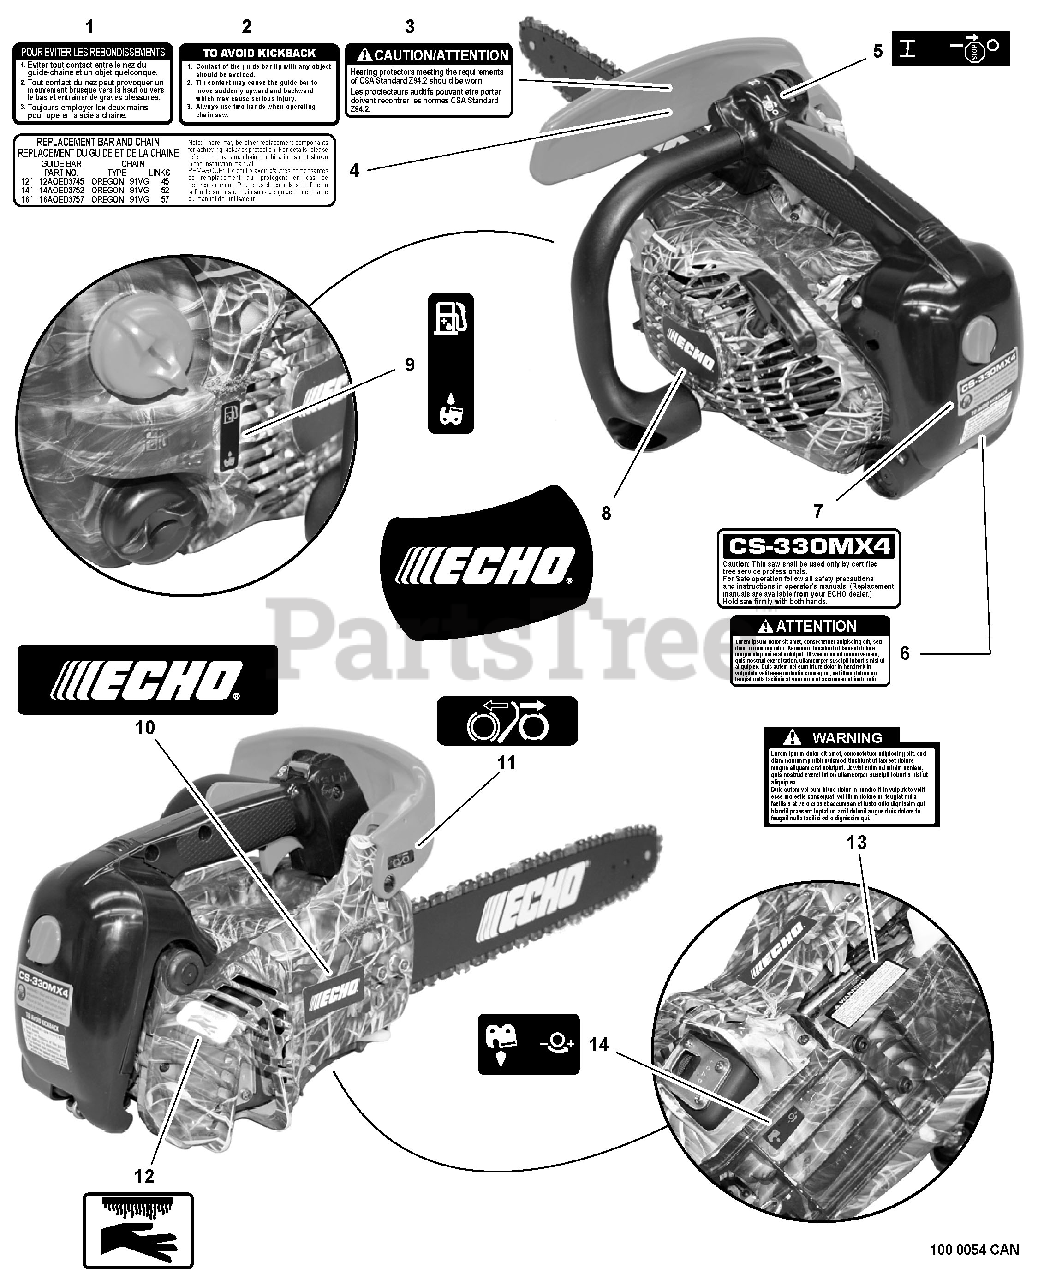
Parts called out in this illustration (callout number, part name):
1	LABEL - KICK BACK
2	LABEL - KICK BACK
3	LABEL - NOISE
4	LABEL - BAR & CHAIN
5	LABEL - STOP
6	LABEL - CAUTION
7	LABEL - MODEL CS-330MX4
8	LABEL - ECHO
9	LABEL - FUEL MIX
10	LABEL - ECHO
11	LABEL - OPERATION
12	LABEL - HOT SURFACE
13	LABEL - WARNING
14	LABEL- CHAIN OIL ADJUSTMENT
